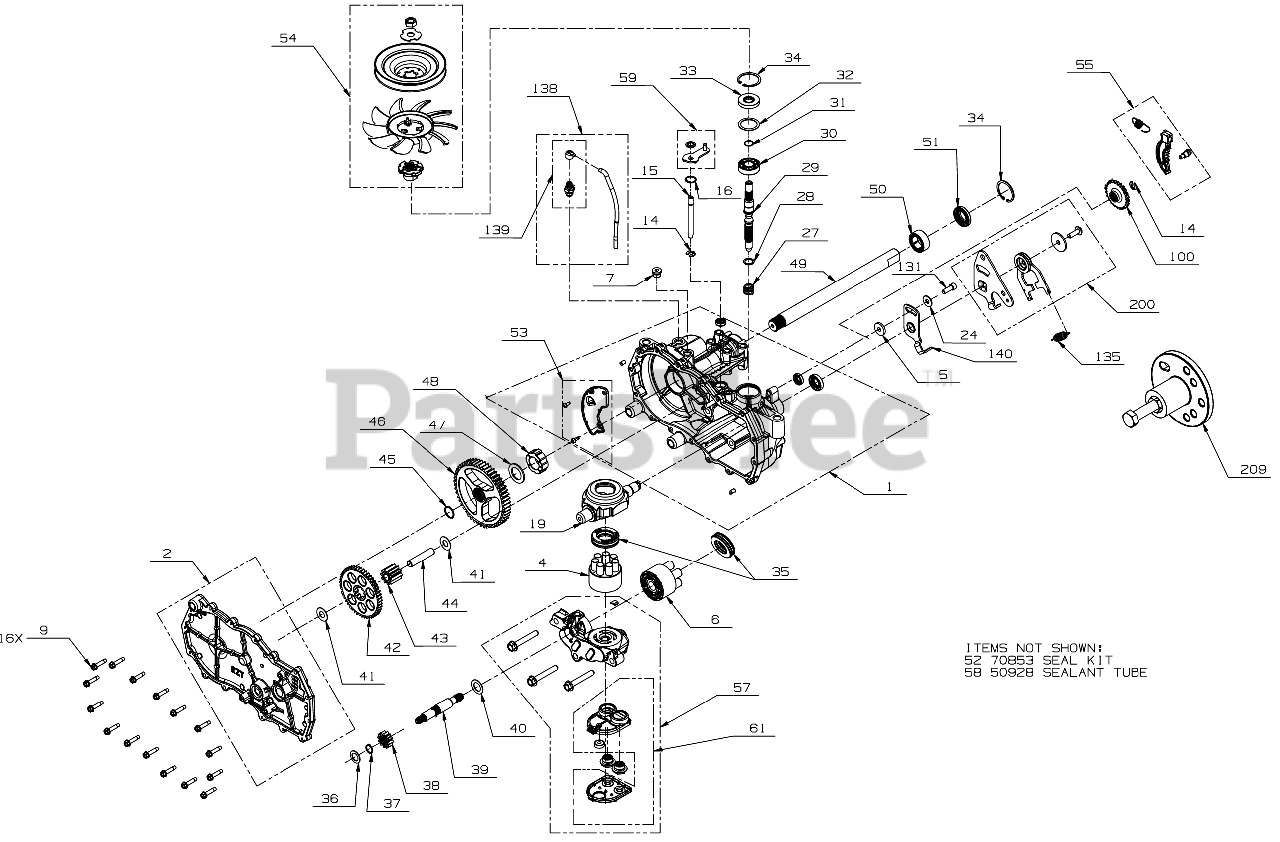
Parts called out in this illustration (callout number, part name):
1	HOUSING KIT-MAIN
2	HOUSING KIT-SIDE
4	BLOCK KIT-7 PISTON
5	SPACER .32 x 1.005 x .179
6	BLOCK KIT-5 PISTON
7	PLUG-STRAIGHT THRE
9	SCREW-WASHER HEAD
14	RETAINING RING
15	BYPASS RODS
16	RETAINING RING
19	SWASHPLATE-TRUNNION
24	FLAT WASHER
27	SPRING-BLOCK
28	THRUST WASHER
29	INPUT SHAFT
30	BALL BEARING
31	RETAINING RING
32	WASHER 1.23X1.56X
34	RETAINING RING
35	THRUST BEARING
36	FLAT WASHER
37	RETAINING RING
38	PINION GEAR 12T
39	MOTOR SHAFT
40	MOTOR SHAFT WASHER
42	GEAR 10T/49T
43	GEAR-10T JACKSHAFT
44	PIN-JACKSHAFT
45	RETAINING RING
46	GEAR-BULL 52T
47	WASHER 1.018 x 1.
48	SLEEVE BEARING
49	AXLE SHAFT
50	SLEEVE BEARING
53	PLATE KIT (LH) EXPANSI
54	KIT-FAN & PULLEY
54	FAN-7.0 (10 BLADE)
54	HUB-PULLEY
54	WASHER-SLOTTED
55	BRAKE ARM KIT
57	SECTION KIT-CENTER
58	SEALANT-HOUSING
59	ARM KIT-BYPASS
61	FILTER ASSEMBLY
100	DISC-BRAKE COG
131	SCREWS KIT-RTN
135	EXTENSION SPRING
138	HOSE KIT-BREATHER
139	CAP KIT-BREATHER
140	ARM-NEUTRAL (LH)
200	RETURN KIT-NEUTRAL (LH) ZT2800 RZT
209	PULLER KIT-HUB
